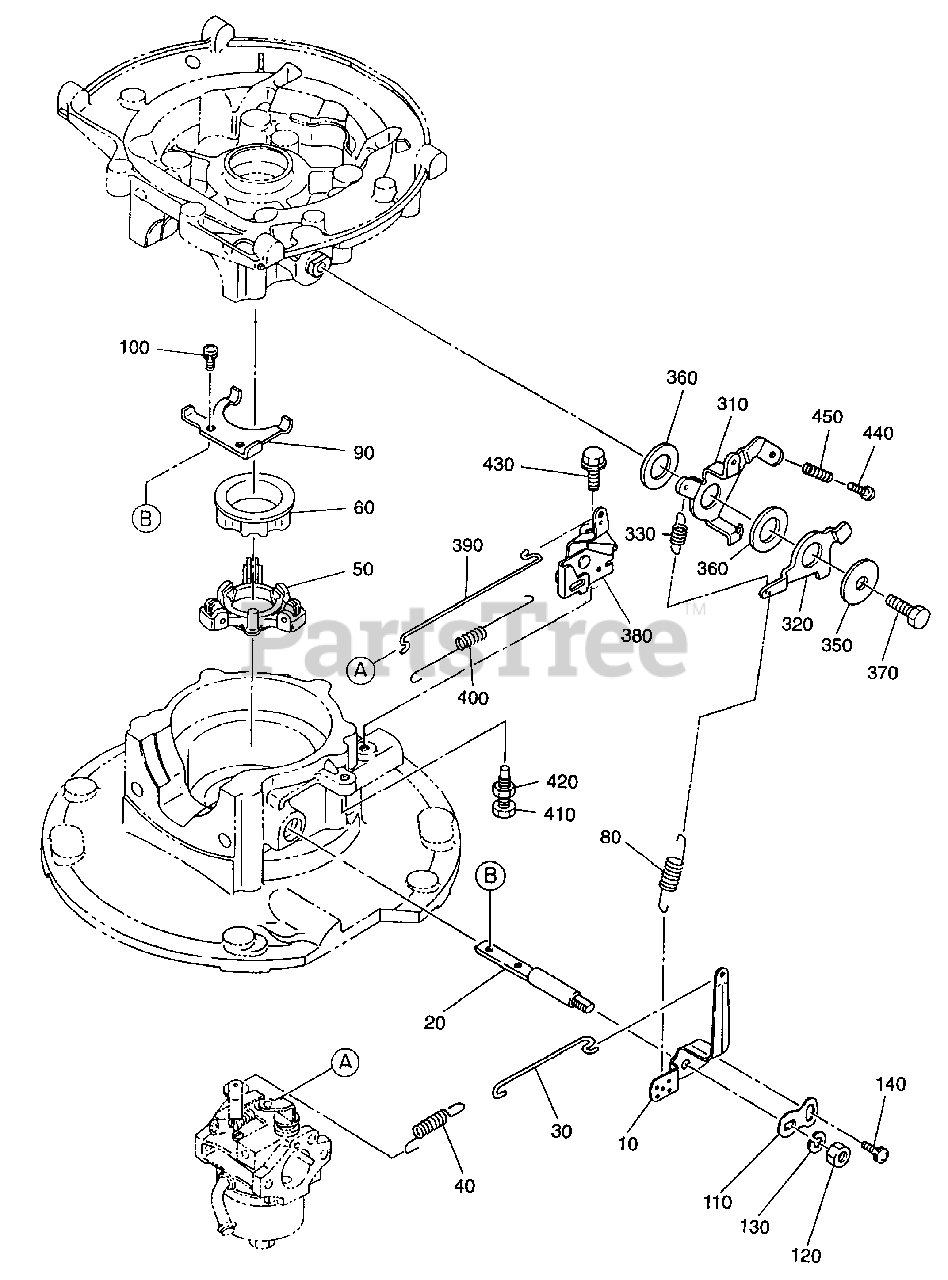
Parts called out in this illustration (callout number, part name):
10	GOVERNOR LEVER
20	GOVERNOR SHAFT
30	GOVERNOR ROD CP
50	GOVERNOR PLATE CP
60	GOVERNOR SLEEVE
80	GOVERNOR SPRING
90	GOVERNOR YOKE
100	SCREW & WASHER ASSY
110	ADJUSTING PLATE
130	SPRING WASHER
140	SCREW & WASHER ASSY
310	SPEED CONTROL LEVER
320	CONTROL LEVER
330	TENTION SPRING
380	CHOKE LEVER CP
390	CHOKE ROD CP
410	SET BOLT CP
430	FLANGE BOLT
440	SCREW, PANHEAD
450	SPRING (ADJUSTER)
